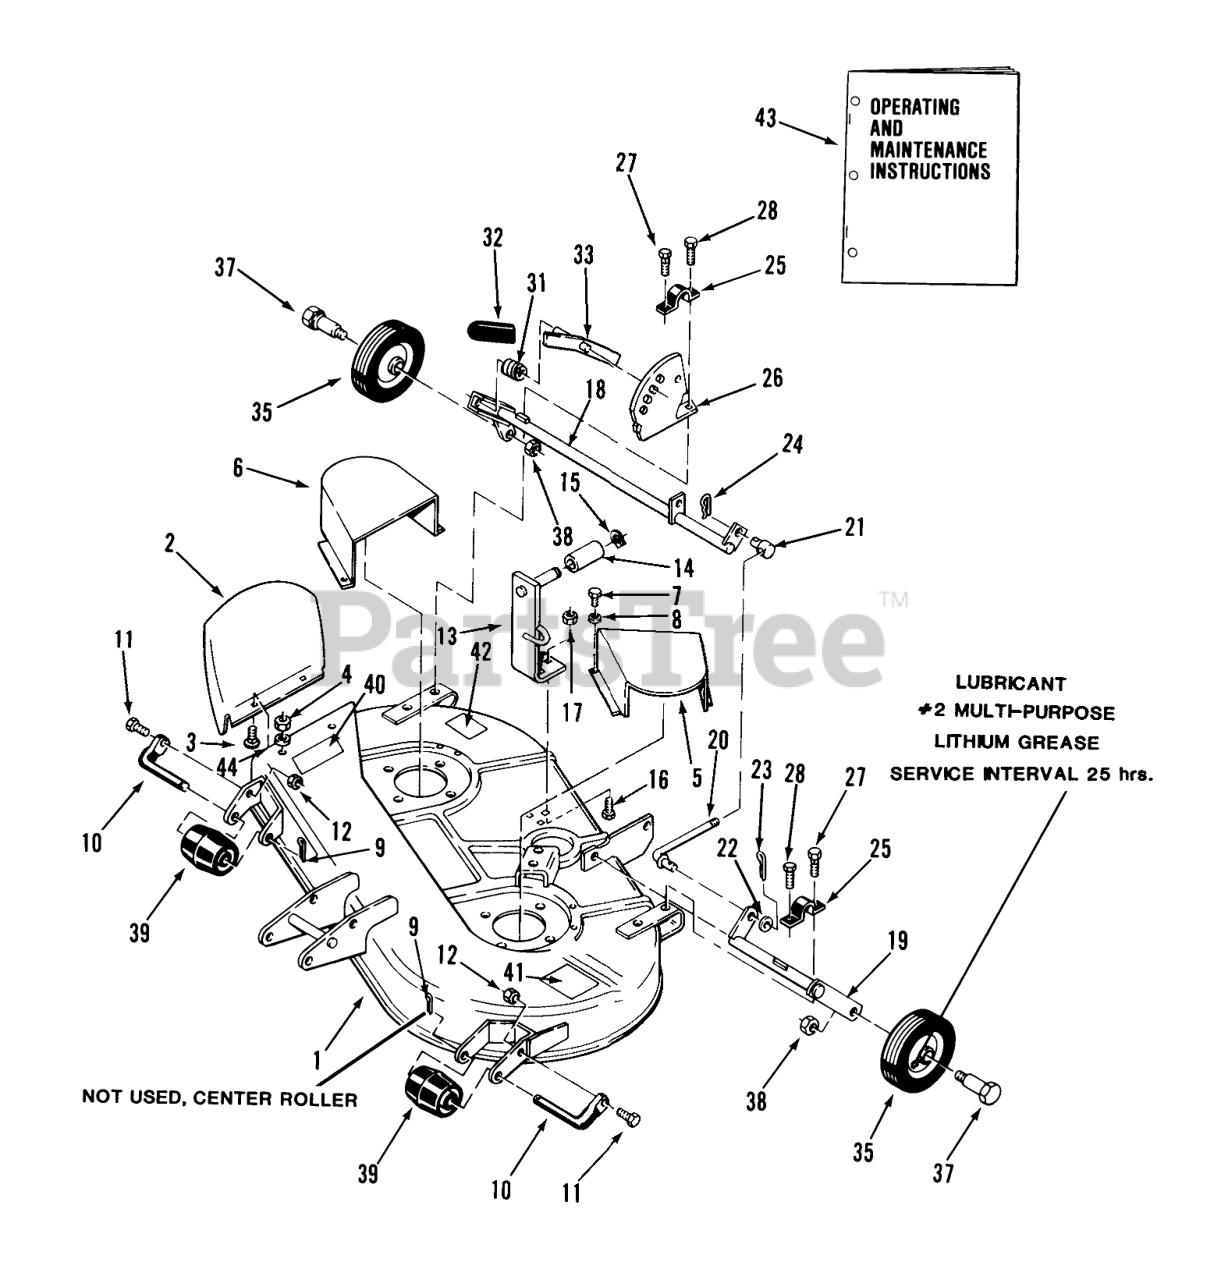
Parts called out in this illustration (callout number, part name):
1	Mower Deck
2	Chute Extension
3	Bolt
4	Nut
5	COVER R
6	COVER R
7	Bolt
8	WASHER
9	Cotter Pin
10	ROLLER-SHAFT
11	H H C S
12	Nut
13	BRACKET ASSY R
14	SPACER
15	Snap Ring
16	BOLT HEX SPECIAL
17	Nut
18	Gage Wheel Support RH
19	WA GAG WHL R
20	ROD CONNECTING
21	TRUNNION
22	Washer
23	Pop Rivet
24	Hairpin
26	QUADRANT R
27	Bolt
28	Bolt
31	SPRING-COMPRESSION
33	Lever
35	WHEEL
37	BOLT-SHOULDER
38	Nut
39	Roller
40	DECAL
41	Caution Decal
42	DECAL-BELT&HEIGHT
43	Operating & Maintenance Instructions
44	WASHER 5/16 SAE
